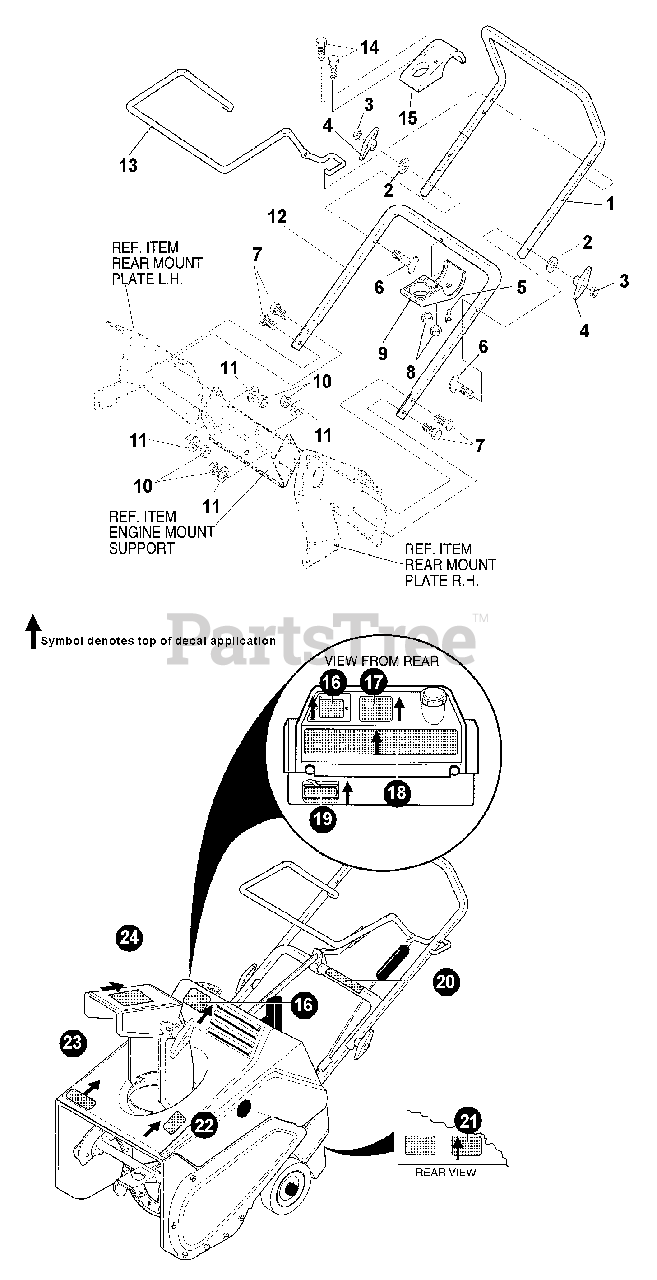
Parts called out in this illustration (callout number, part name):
1	HANDLE ASSY - UPPER
2	WASHER
3	NUT - 5/16-18
4	KNOB, T 2 BLADE W/5/16-18 NUT
5	SCREW - 1/4-20 X .63" -- TAPPING
6	BOLT, 5/16-18 X 2.00
7	SCREW - 5/16-18 X 3/4"
8	LOCKNUT - 10-24
9	BRKT HALF, CHUTE CRANK
10	NUT - 5/16-18
11	WASHER
12	HANDLE - LOWER
13	BAR, DRIVE CONTROL LOOP
14	SCREW - 10-24 X 1.00"
15	BRKT HALF, CHUTE CRANK
16	LABEL - ECHO -- ST-5000E
17	LABEL - STARTING
18	LABEL - CONTROL PANEL
19	LABEL - CHOKE
20	LABEL - AUGER CONTROL BAR
21	LABEL - EPA
22	LABEL - DANGER
23	LABEL - ECHO
24	LABEL - DANGER
